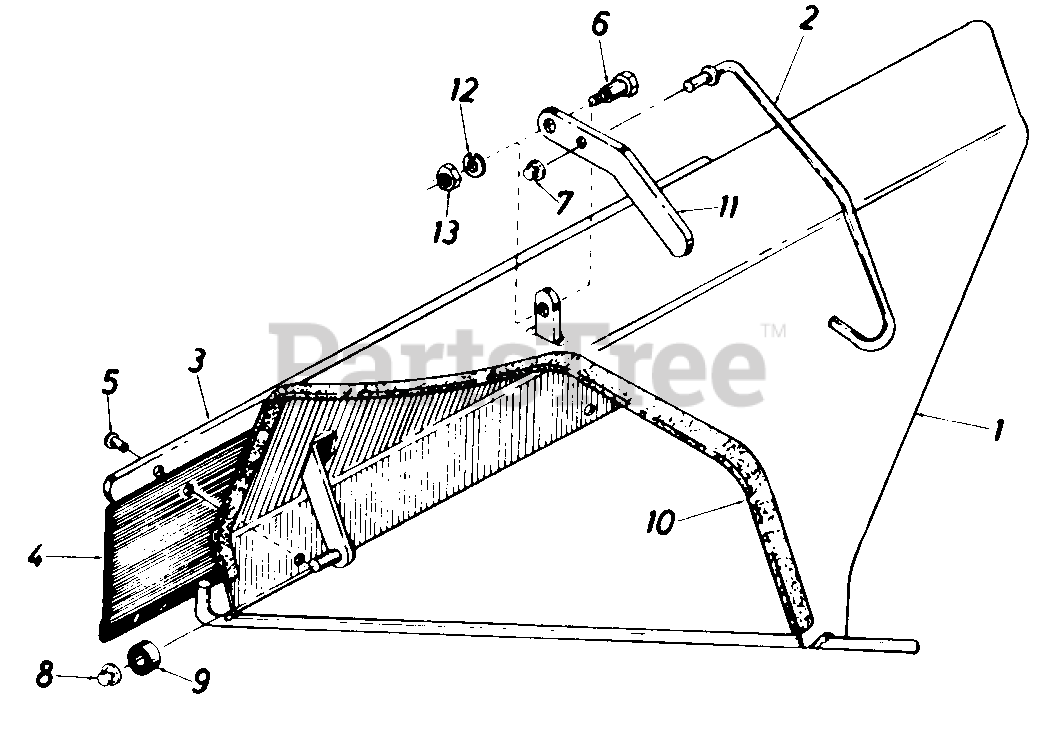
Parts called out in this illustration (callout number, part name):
1	DEFLECTOR ASSY
2	HOOK ASSY
3	STRIP-RETAINING
5	RIVET-POP
6	SCREW-SHLD
9	ROLLER-PLASTIC
10	STRIP-TRIM-12IN
11	LATCH-ARM
12	LOCK WASHER 1/4 DIA
13	NUT-HEX 1/4-20
